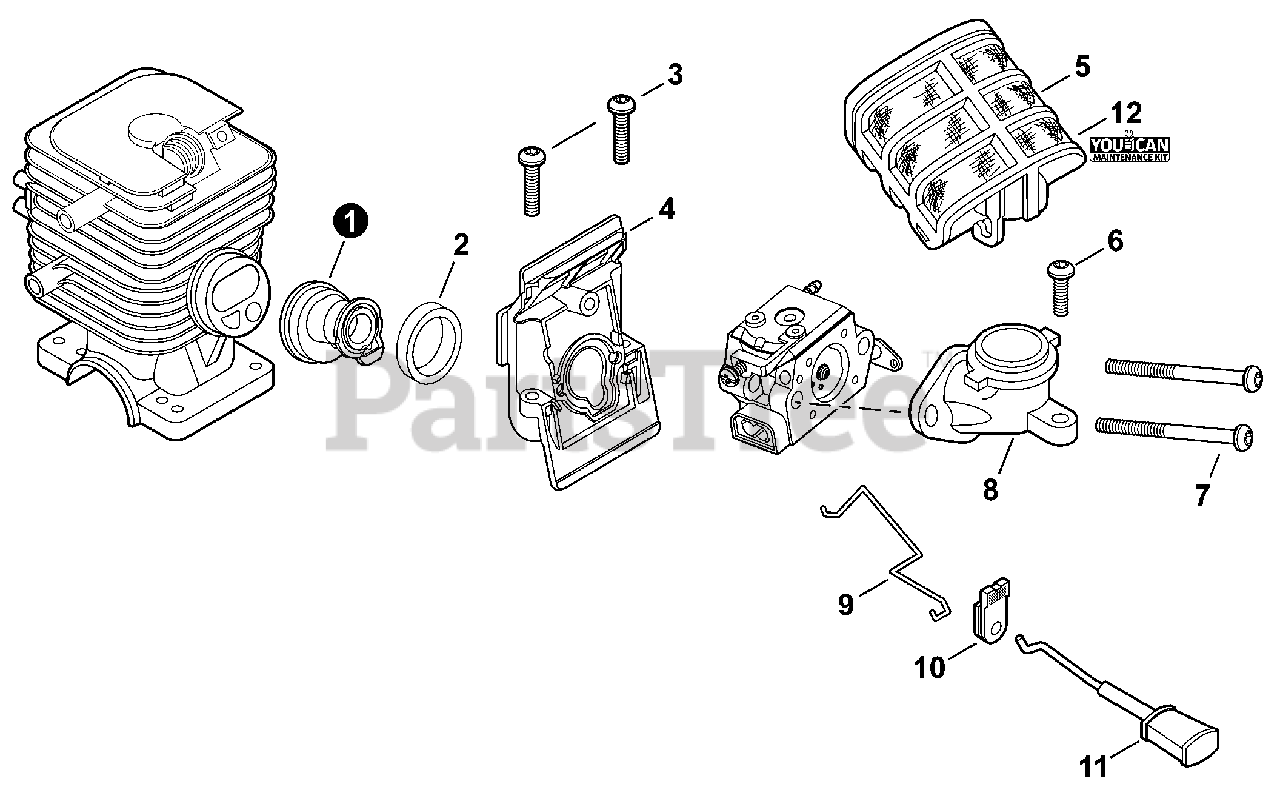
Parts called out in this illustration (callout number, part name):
1	BELLOWS, INTAKE
2	RETAINER, BELLOWS
3	BOLT, TORX 5×20
4	INSULATOR, INTAKE
5	FILTER ASSY, AIR
6	BOLT, TORX 5×16
7	BOLT, TORX 5×55
8	BRACKET, AIR FILTER
9	ROD, THROTTLE
10	GROMMET, CHOKE
11	ROD, CHOKE
12	TUNE-UP KIT - YOUCAN™
